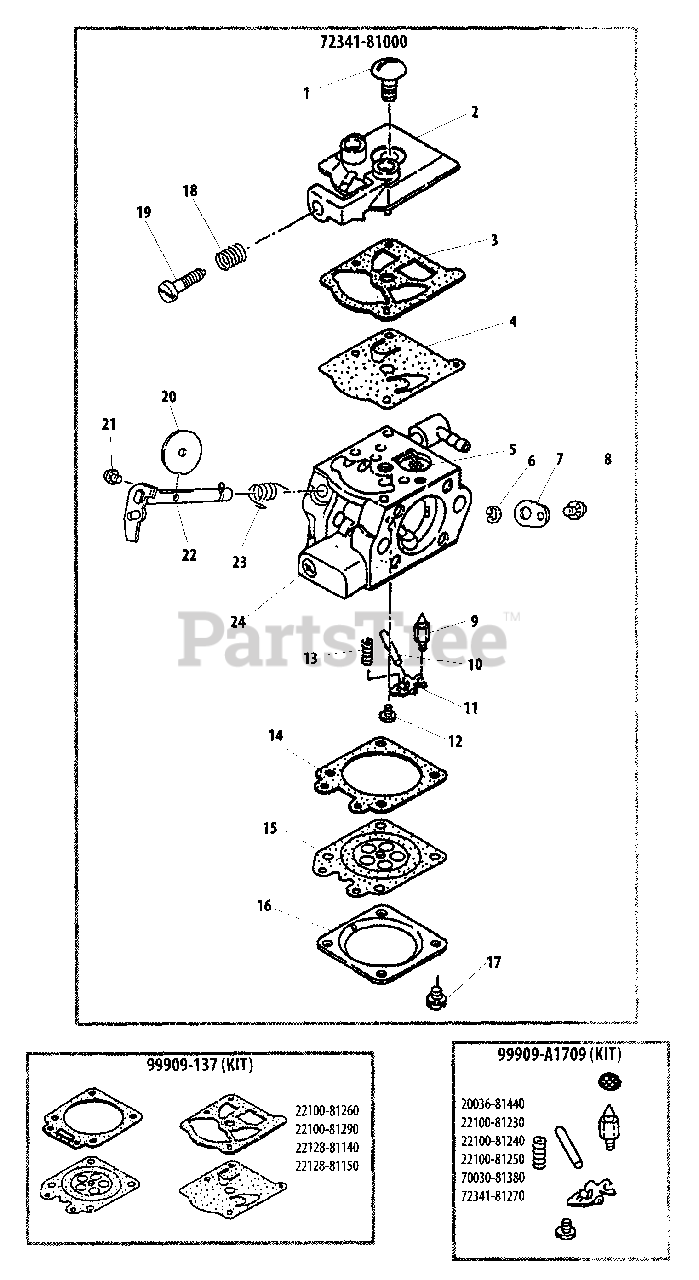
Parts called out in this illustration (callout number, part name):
1	SCREW, PUMP COVER
2	COVER, PUMP
3	GASKET, PUMP
4	DIAPHRAGM, PUMP
5	STRAINER
6	RING, RETAINING
7	LEVER, THROTTLE
8	SCREW
9	VALVE, INLET NEEDLE
10	PIN, METERING LEVER
11	LEVER, METERING
12	SCREW, METERING LEVER PIN
13	SPRING, METERING LEVER
14	GASKET, METERING
15	DIAPHRAGM, METERING
16	COVER, DIAPHRAGM
17	SCREW
18	SPRING
19	SCREW, IDLE ADJUST
20	VALVE, THROTTLE
21	SCREW
22	SHAFT, THROTTLE
23	SPRING, THROTTLE RETURN
24	CAP, LIMITER
72341-81000	CARBURETOR
99909-137	DIAPHRAGM/GASKET KIT
99909-A1709	REPAIR KIT
